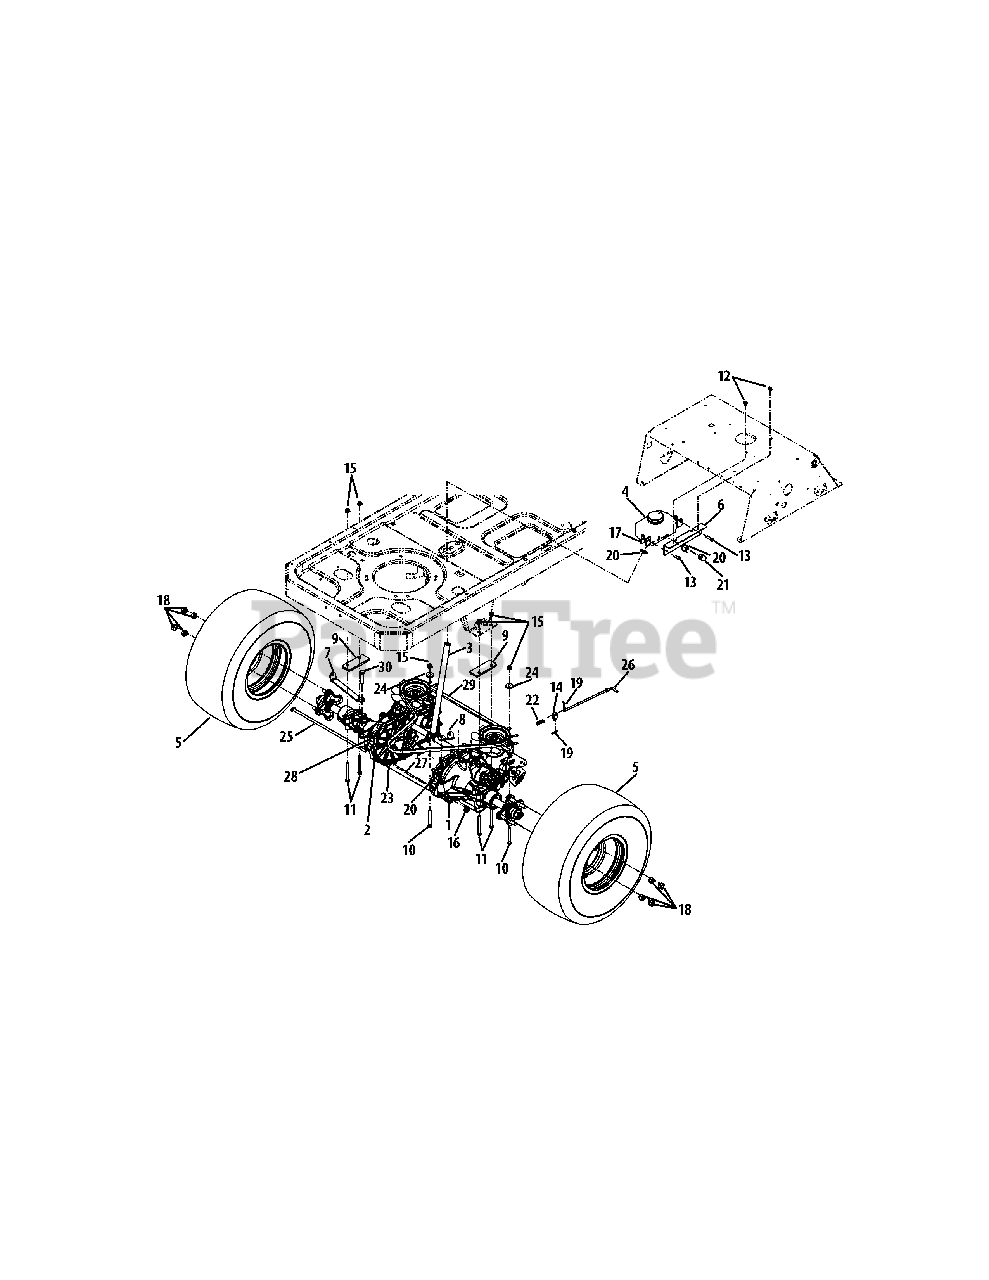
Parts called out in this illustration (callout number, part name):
1	Transmission Assembly (RH)
2	Transmission Assembly (LH)
3	Breather
4	Expansion Tank Assembly
5	Wheel Assembly, 20 x 10 x 8
6	Expansion Tank Bracket
7	Transmission Brace (LH)
8	Transmission Brace (RH)
9	Transmission Spacer
10	Hex Screw, 5/16-18 x 2.75
11	Hex Screw, 5/16-18 x 3.00
12	Screw, 1/4-20 x .500
13	Screw, 1/4-20 x 1.000
14	Ferrule, .325 x .312
15	Flange Lock Nut, 5/16-18
16	Flange Lock Nut, 3/8-16
17	Speed Nut, 1/4-20
18	Lug Nut, 7/16-14
19	Bow-Tie Cotter Pin
20	Hose Clamp, 1/2
21	Cap, 1/2 x .870
22	Compression Spring, .405 x 1.17
23	Extension Spring, .545 x 4.555
24	Flat Washer, .35 x 1.0 x .2
25	Rod, .337 x 14.75
26	Bypass Rod
27	Tube, 7/16 x 3/4 x 11.3
28	Straight Fitting, 9/16 x 1/2
29	V-Type Belt
30	Hex Screw, 5/16-18 x 2.25
